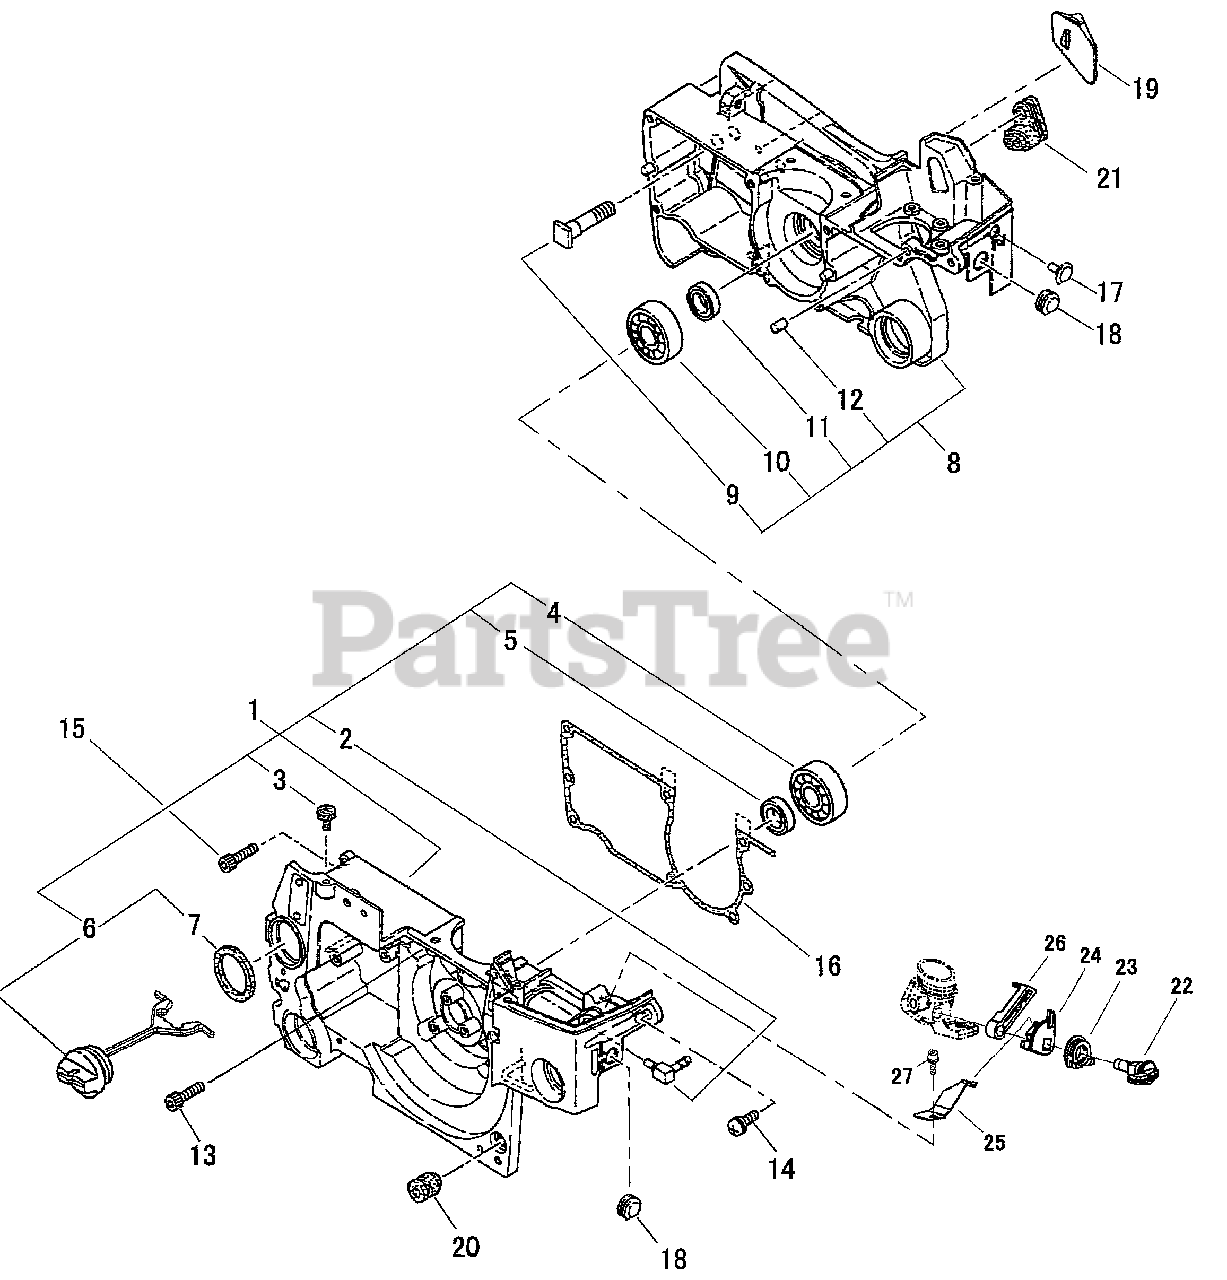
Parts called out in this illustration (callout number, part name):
1	CRANKCASE ASSY, M
2	CONNECTOR, PIPE
3	VENT ASSY
4	BEARING, BALL 6201C3
5	SEAL, OIL 12
6	CAP ASSY
7	GASKET
8	CRANKCASE ASSY, C
9	BOLT, STUD 8
10	BEARING, BALL 6201C3
11	SEAL, OIL 12
12	PIN, LOCATING 5×10
13	BOLT M5×30
14	SCREW
15	BOLT M5×18
16	GASKET
17	CLAMP - A
18	PLUG
19	STOPPER
20	SUPPORT
22	SWITCH, ON-OFF
24	CAP, IGNITION SWITCH
25	PLATE, SPRING
26	CHOKE
27	BOLT M4×10
